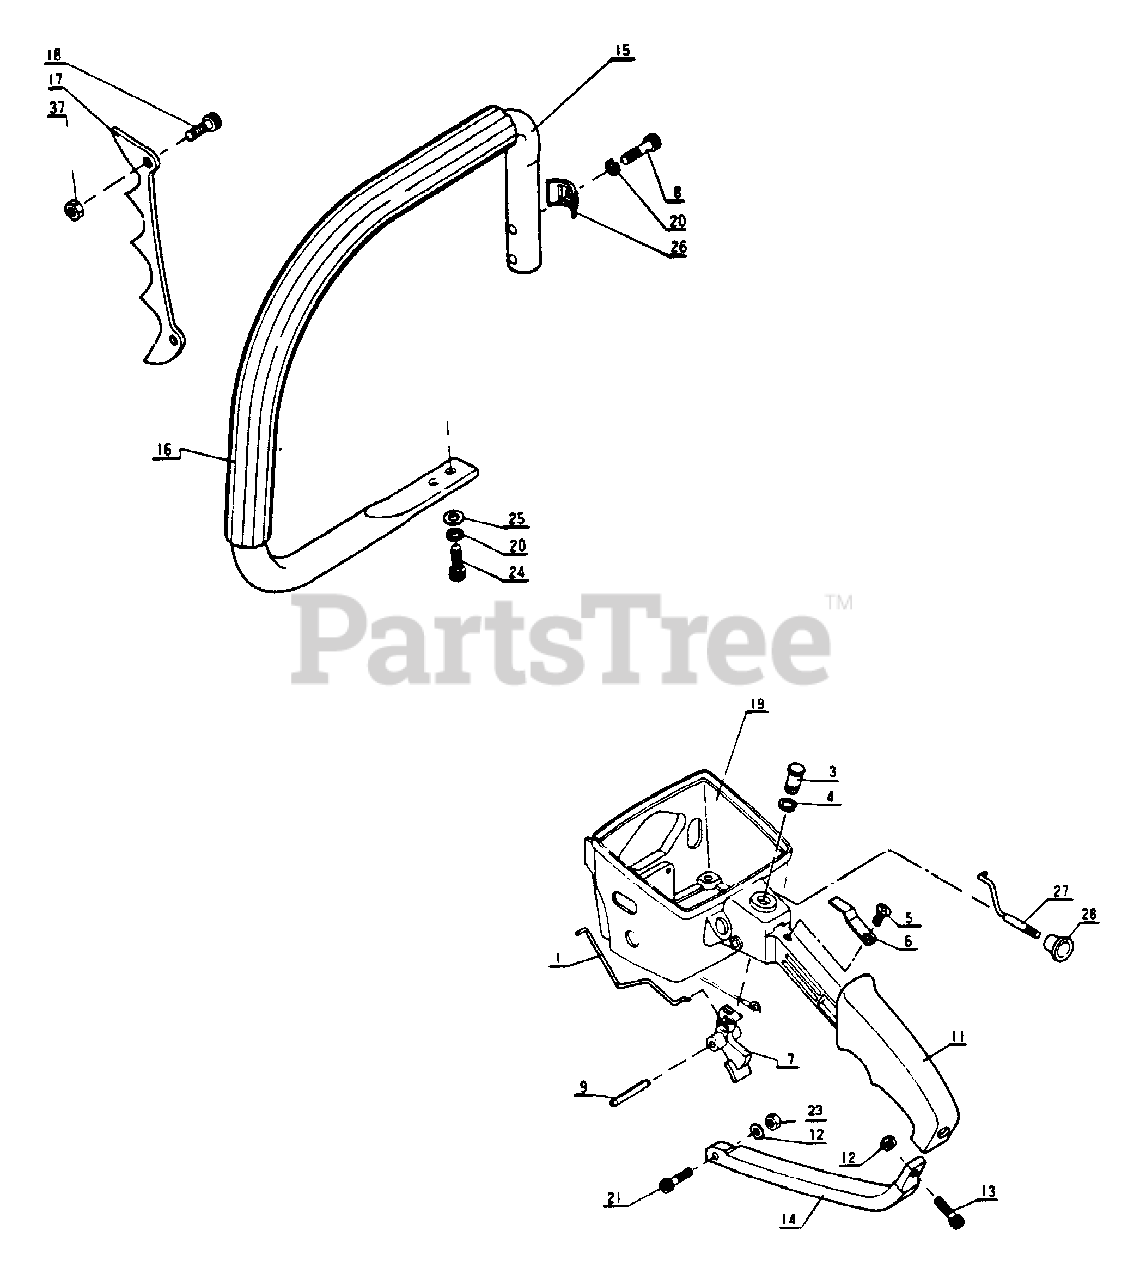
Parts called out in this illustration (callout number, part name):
1	ROD, CHOKE
3	LOCKOUT, THROTTLE
4	RING, RETAINING - 6
5	SCREW
5	SCREW - 5×8
6	LEAF SPRING
7	TRIGGER, THROTTLE
8	BOLT
11	RIGHT HANDLE RUBBER
12	NUT
12	NUT M5
13	BOLT
13	BOLT - 5×25
14	RIGHT HANDLE SUPPORTER
15	LEFT HANDLE
16	HANDLE, FRONT
17	BUMPER, SPIKED
18	BOLT
18	BOLT - 5×18
19	RIGHT HANDLE
20	WASHER, SPRING 6
21	BOLT
21	BOLT - 5×30
23	NUT
23	LOCKNUT - 5
24	BOLT
25	WASHER 6.5×11.5×0.8
26	HANDLE SET PLATE
27	ROD, CHOKE
37	NUT
